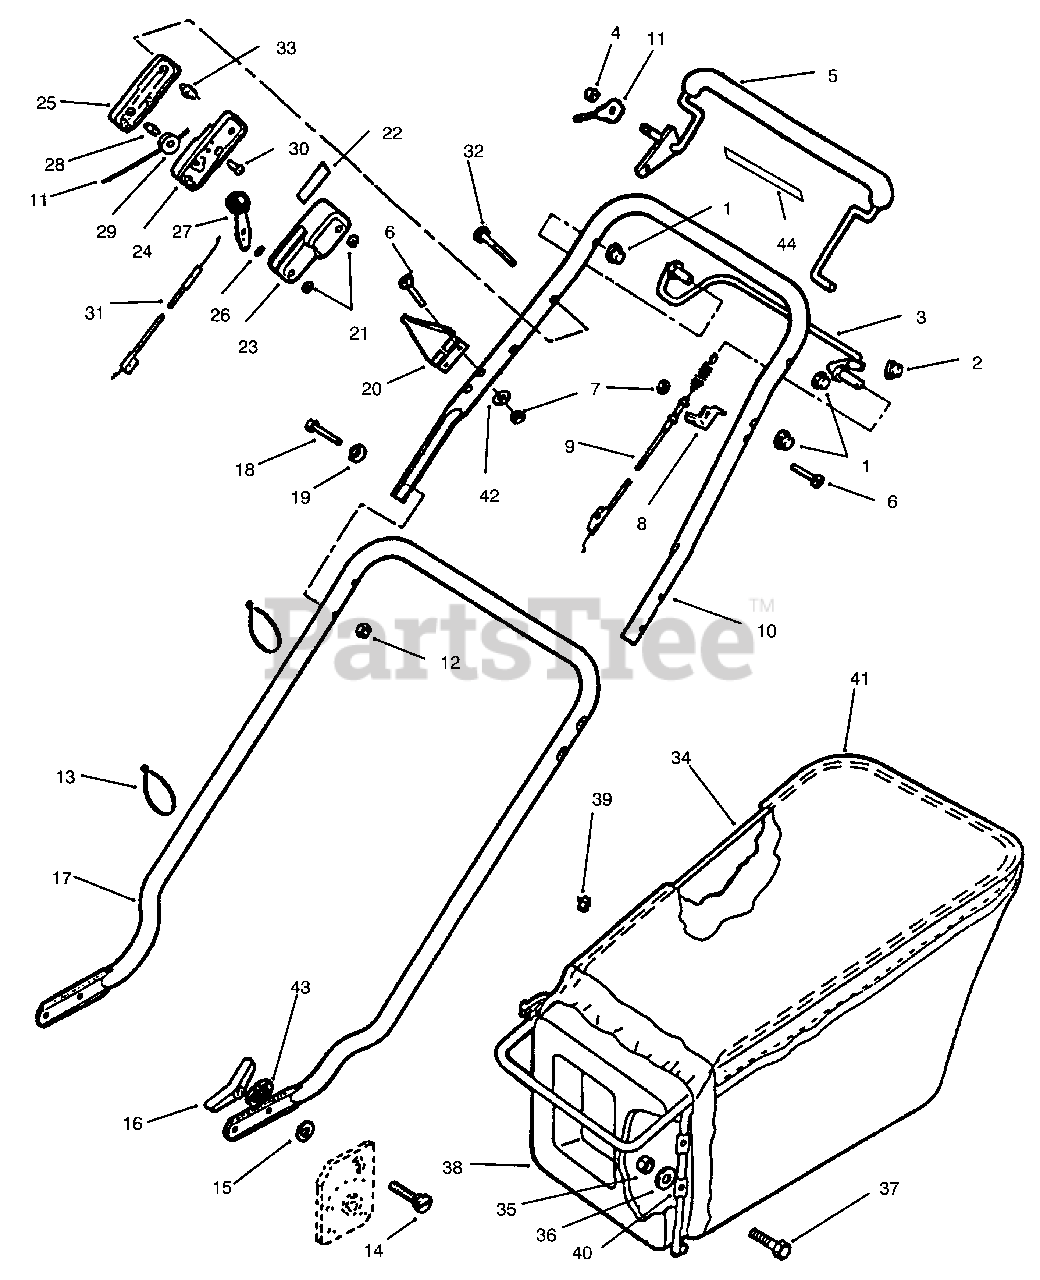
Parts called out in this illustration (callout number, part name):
1	Palnut-Bails to Handle
2	Palnut-Cable to Bail
3	Bail-Self Propelled
4	Nut-Acorn, Cable to Bail
5	Bail-Brake, Engine
7	Nut-Lock
8	Anchor-Conduit
9	Cable-Control
10	Handle-Top
11	Assy.-Cable, Control
12	Nut-Lock
13	Strap-Tie
14	Bolt
15	Washer-Lock, Ext. Tooth
16	Nut-Wing
17	Handle-Lower
18	Screw
19	Washer-Curved
20	Guide-Rope
22	Decal-Control, Throttle
23	Case-Control, Inner
24	Case-Control, Center
25	Case-Control, Outer
26	Washer-Spring
27	Lever & Knob, Throttle
31	Cable-Throttle
34	Hanger-Bag
35	Nut-Lock
37	Screw
38	Adaptor
39	"S" Clip
40	Bar-Latch
41	Bag-Grass
43	Washer-Lock
44	Decal-Traction
